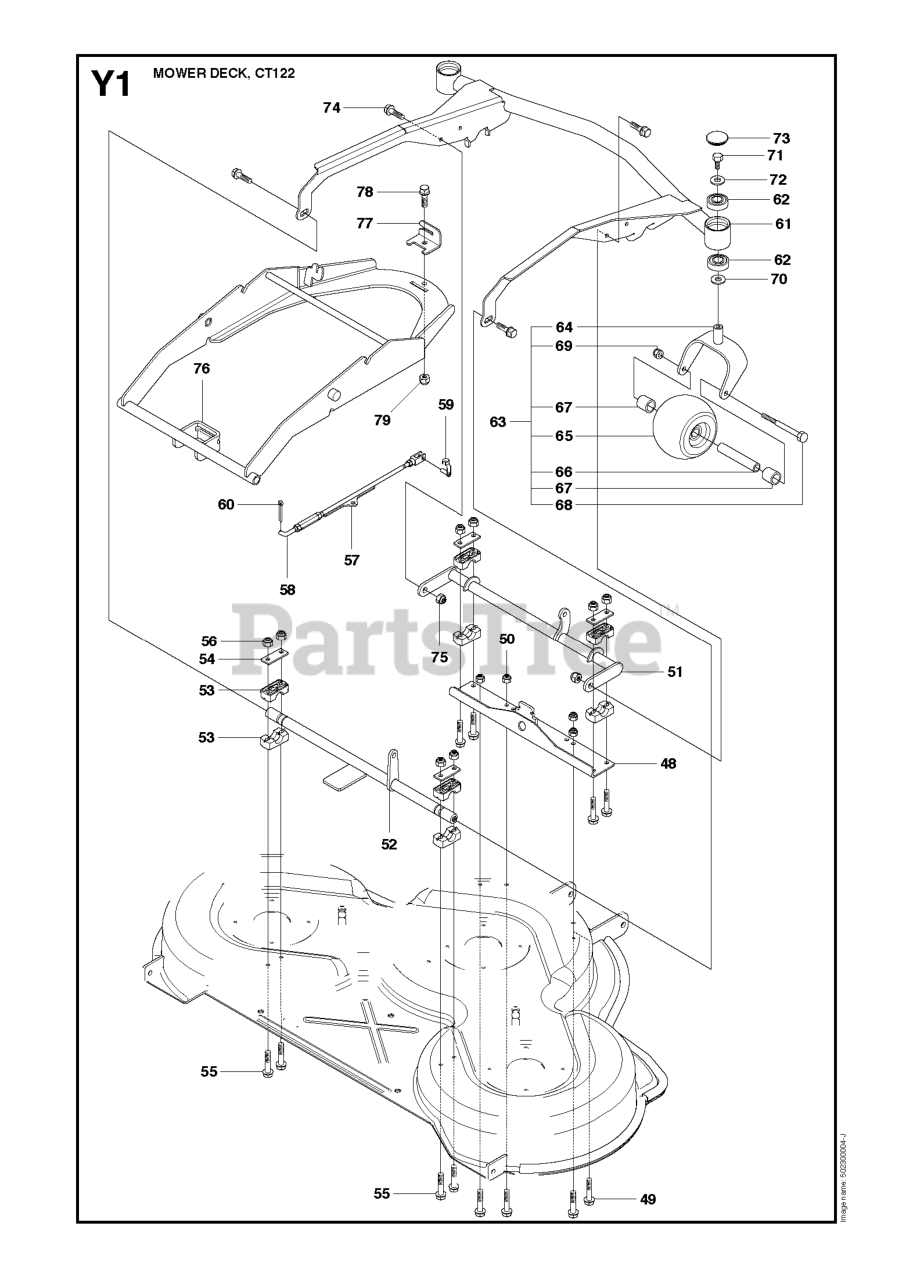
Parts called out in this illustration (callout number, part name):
50	LOCKNUT M8
56	LOCKNUT M8
58	PARALLEL ROD
62	BALL BEARING 6004-2RS1
63	PIVOT WHEELS
64	CLEVIS
65	DECK ROLLER, FRONT
69	NUT
73	HUB CAP PIVOT WHEEL
75	LOCKNUT M8
79	LOCKNUT M8
